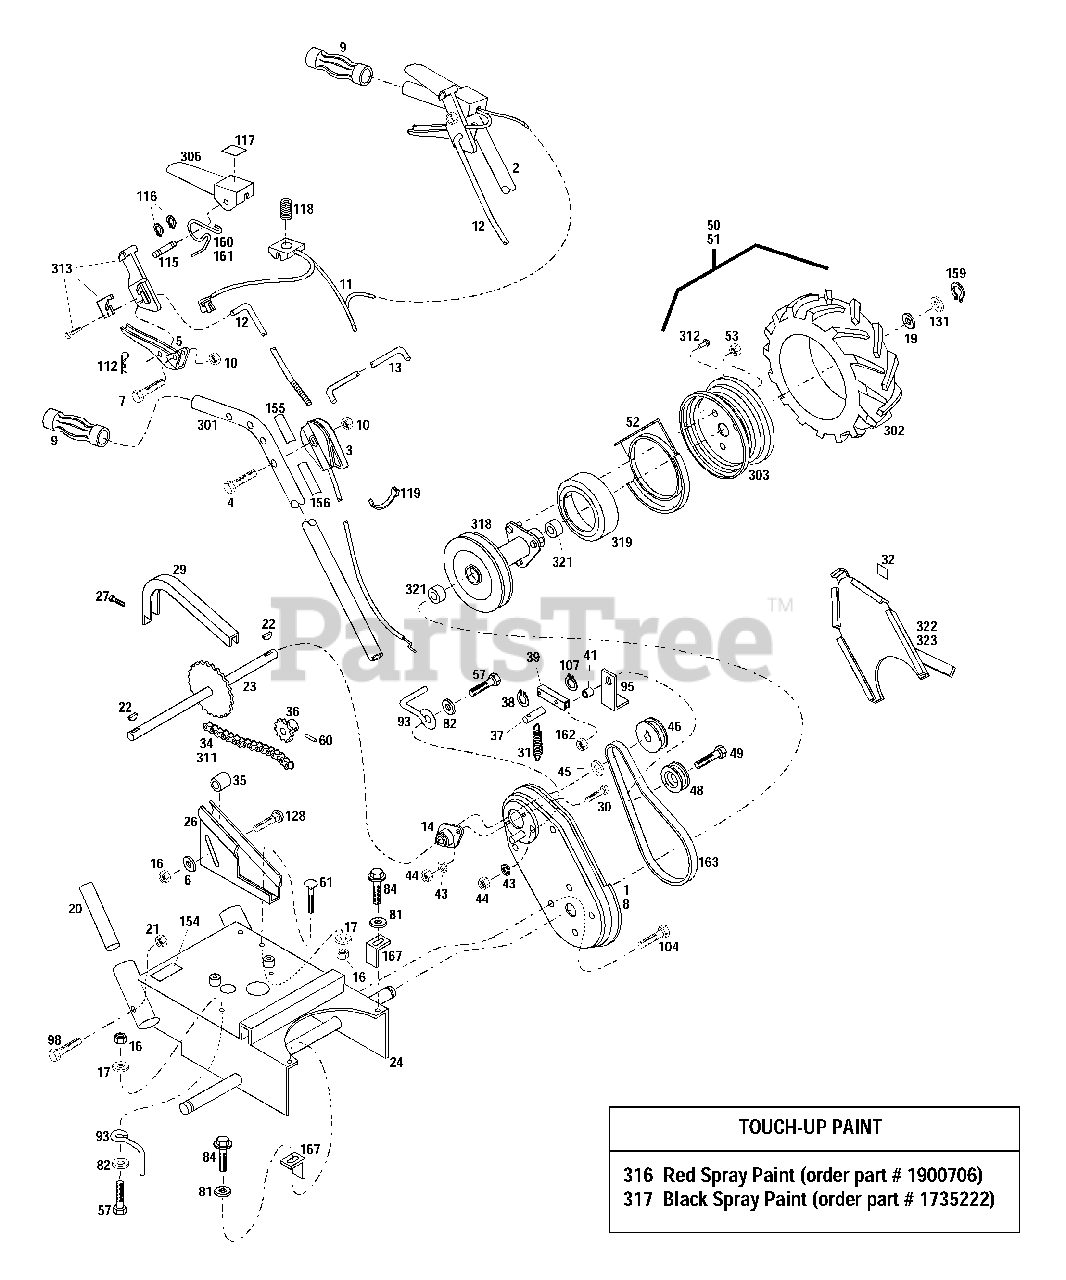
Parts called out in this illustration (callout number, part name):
1	Left Wheel Drive Housing
2	Left Handlebar
3	Throttle
4	Hex Head Capscrew, 1/4-20 x 2
5	Wheel Clutch Lever
6	Flat Washer, 5/16
7	Hex Head Capscrew, 1/4-20 x 1-1/2
8	Right Wheel Drive Housing
9	Handle Grip
10	Center Locknut, 1/4-20
11	Operator Interlock Harness
12	Wheel Clutch Rod
13	Handlebar Bridge
14	Flange Bearing
16	Hex Nut, 5/16-18
17	Lockwasher, 5/16
19	Flat Washer, 3/4
20	Shock Absorber
21	Top Locknut, 5/16-18
22	Woodruff Key, #9, 3/16 x 3/4
23	Counter Shaft
24	Engine Deck
26	Chain Idler Bracket
27	Hex Head Screw, #10-24 x 1/2
29	Chain Cover
30	Carriage Bolt, 1/4-20 x 1/2
31	Wheel Clutch Spring
32	Decal, Top
34	Chain
35	Chain Idler
36	Sprocket, 12T
37	Idler Arm Pivot
38	Snap Ring, 3/8, "E" Type
39	Wheel Clutch Idler Arm
41	Wheel Idler Spacer
43	Lockwasher, 1/4
44	Hex Nut, 1/4-20
45	Spacer
46	Counter Shaft Pulley
48	Idler Pulley
49	Hex Head Capscrew, 3/8-16 x 2-1/4
50	Left Wheel Assembly
51	Right Wheel Assembly
53	Top Locknut, 3/8-24
57	Hex Head Capscrew, 5/16-18 x 3/4
60	Roll Pin, 3/16 x 1
61	Carriage Bolt, 5/16-18 x 3/4
81	Flat Washer (hardened), 5/16
82	Flat Washer, 5/16
84	Hex Head Capscrew, 3/8-16 x 3/4, Grade 8
93	Belt Guide
95	Belt Guide
98	Hex Head Capscrew, 5/16-18 x 2-1/4, Grade 5
104	Self-Tapping Screw, 5/16-18 x 5/8
107	Retaining Ring, 1/2
115	Pivot Pin, 1/4
116	Crescent Ring
117	Decal, Operator Presence Control
118	Compression Spring
119	Cable Tie
128	Carriage Bolt, 5/16-18 x 1-1/4
131	Shim Washer
154	Decal, Oil Drain
155	Decal, Throttle
156	Decal, Place Hand
159	Retaining Ring
160	Left Control Return Spring
161	Right Control Return Spring
162	Center Locknut, 3/8
167	Belt Guide
301	Right Handlebar Assembly
302	Tire, 13 x 5 x 6 Traction Lug
303	Wheel Rim Assembly
306	Operator Presence Control Lever Assembly
311	Chain Connector Link
312	Valve Stem
313	Thumb Latch Assembly
316	Red Spray Paint (13 oz. can)
317	Black Spray Paint (13 oz. can)
318	Drive Hub/Pulley
319	Spacer Tube
321	Bearing
322	Right Belt Cover Assembly
323	Left Belt Cover Assembly
